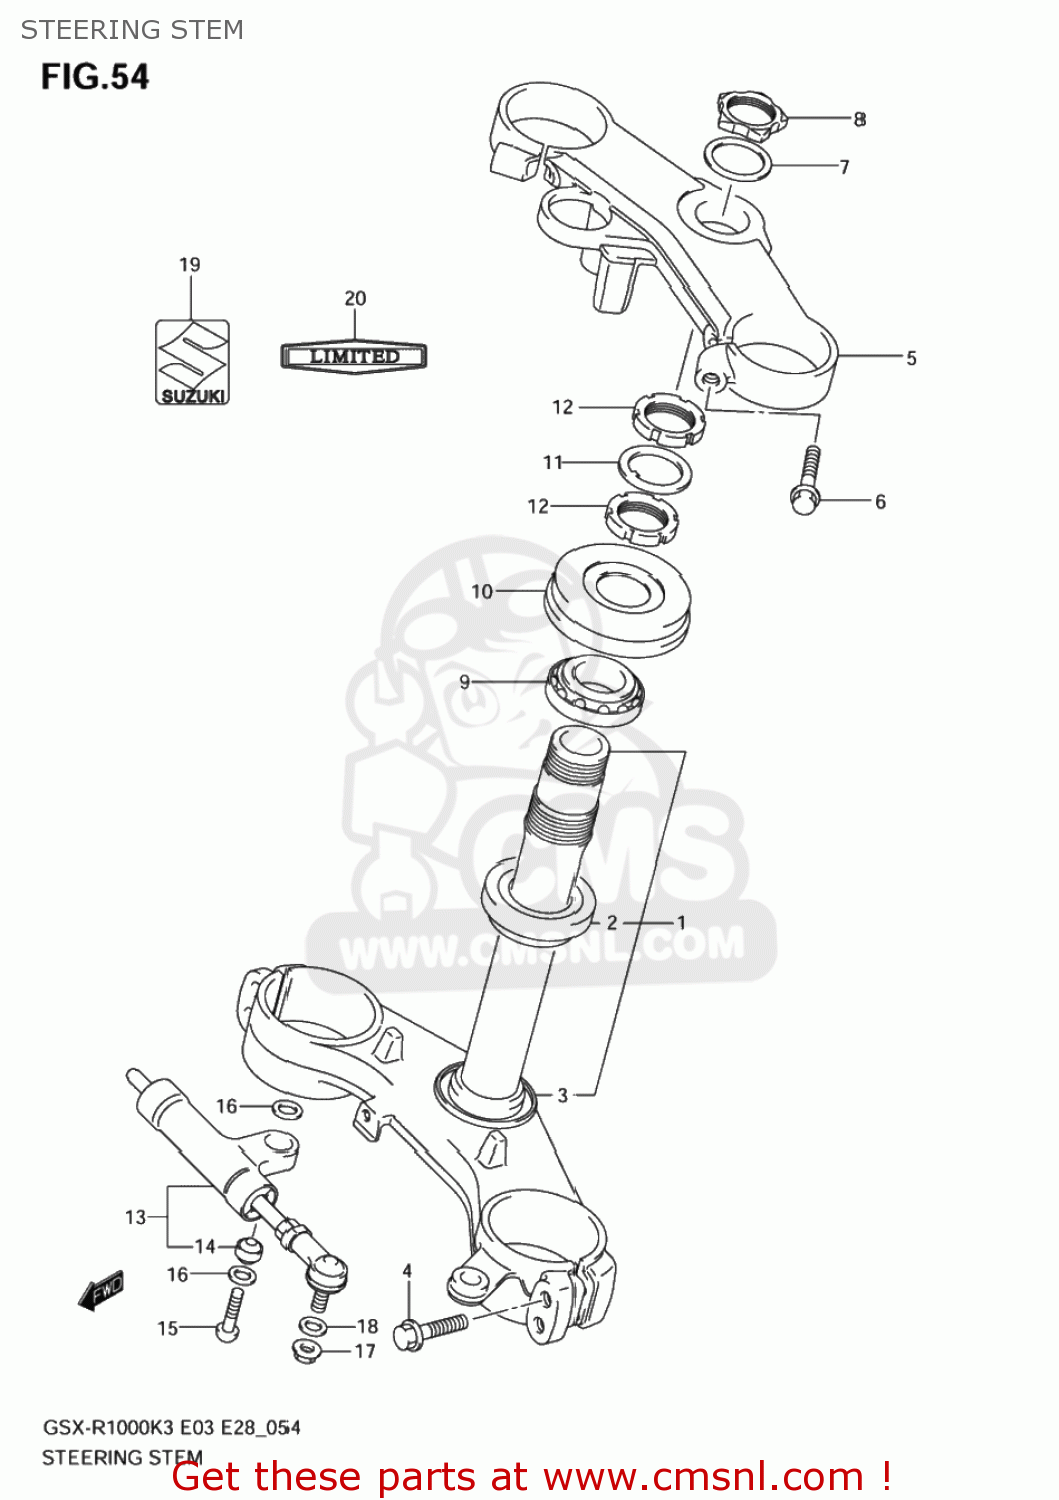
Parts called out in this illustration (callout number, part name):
1	BRACKET,FR FORK UNDER
2	BEARING(30X55X17)
3	SEAL,STEERING LWR
4	BOLT
5	BRACKET,FR FORK UPR
6	BOLT
7	WASHER
8	NUT
9	BEARING(30X55X17)
10	SEAL,STEERING UPR DUST
11	WASHER,STEERING STEM
12	NUT,STEERING STEM
13	DAMPER ASSY,STEERING
14	BEARING(8X17.5X11)
15	BOLT(8X35)
16	SEAL,PILLOW BALL,DUST
17	NUT
18	WASHER(8.5X18X1.6)
19	EMBLEM,S
20	EMBLEM,LIMITED
